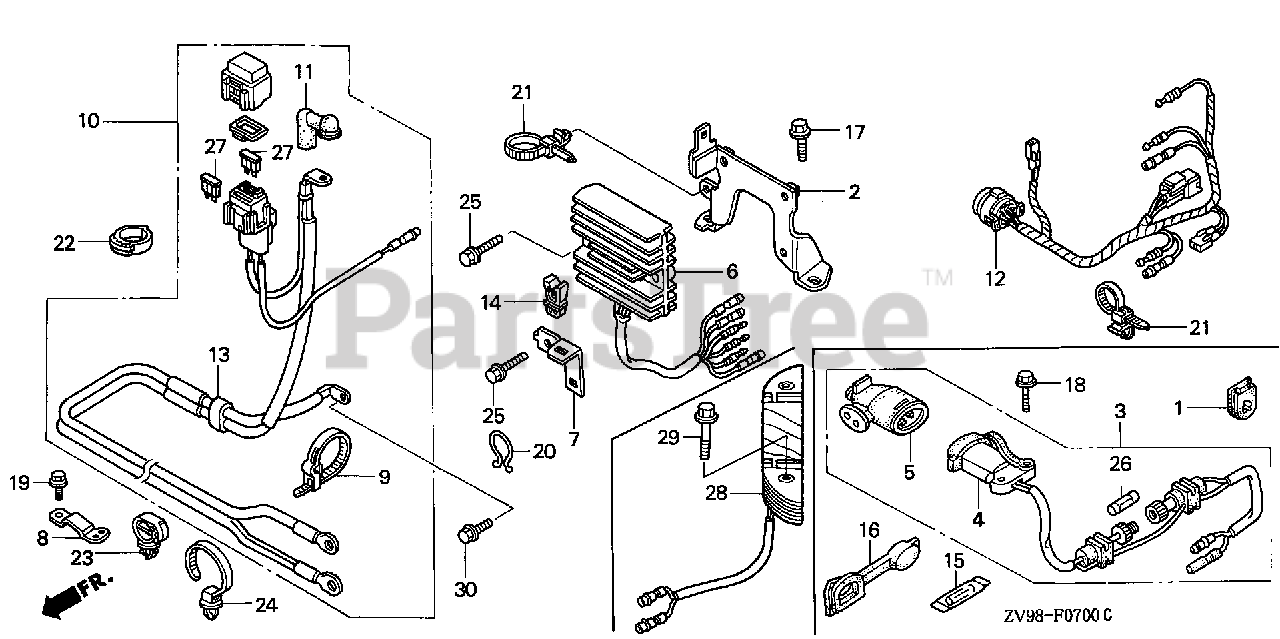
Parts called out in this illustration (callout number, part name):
1	GROMMET, WIRE
2	BRACKET, REGULATOR
3	RECEPTACLE ASSY., CHARGE
4	RECEPTACLE
5	PLUG, RECEPTACLE
6	RECTIFIER ASSY., REGULATOR
15	FUSE, SPARE (15A)
16	GROMMET, CASE (LOWER) (C)
17	BOLT, FLANGE (6X12)
18	BOLT, FLANGE (5X22)
21	STRAP, CABLE (118MM) (BLACK)
25	BOLT, FLANGE (6X20)
26	FUSE (15A)
28	COIL ASSY., CHARGE (12V-6A)
29	BOLT, FLANGE (6X35)
